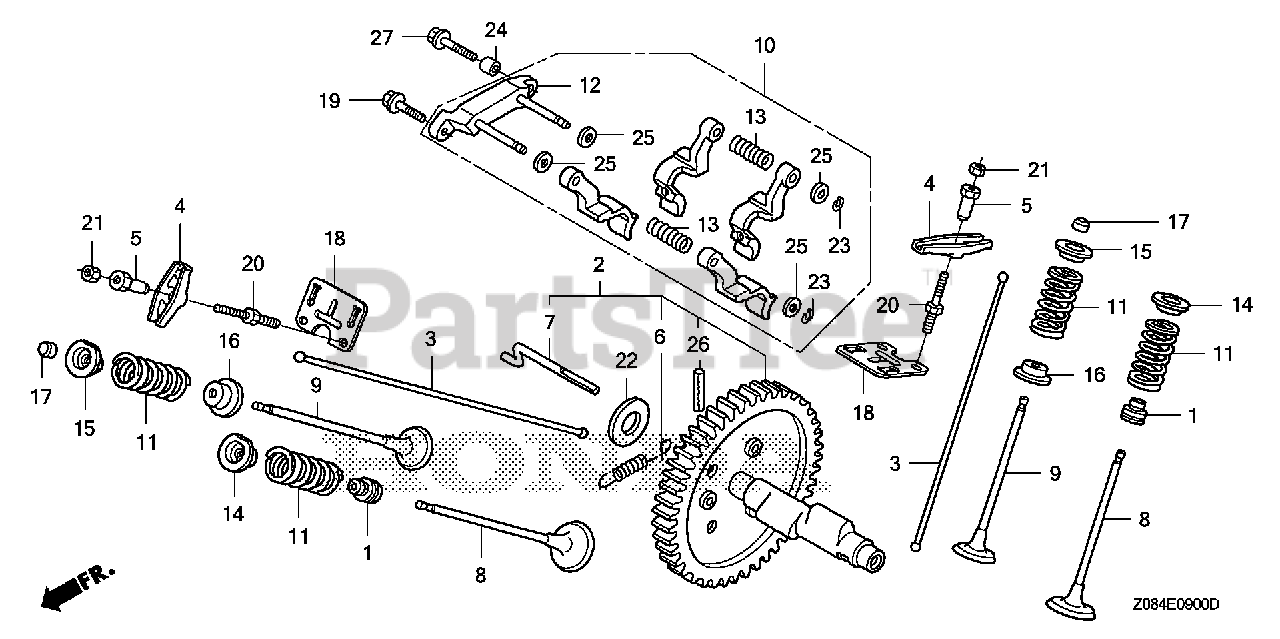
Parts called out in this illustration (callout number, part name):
1	SEAL, VALVE STEM
2	CAMSHAFT ASSY.
4	ARM, VALVE ROCKER
5	PIVOT, ROCKER ARM
6	SPRING, WEIGHT RETURN
7	PIN, DECOMPRESSION
8	VALVE, IN.
9	VALVE, EX.
10	LIFTER ASSY., VALVE
11	SPRING, VALVE
12	SHAFT, VALVE LIFTER
13	SPRING, VALVE LIFTER
14	RETAINER, IN. VALVE SPRING
15	RETAINER, EX. VALVE SPRING
16	SEAT, VALVE SPRING
17	ROTATOR, VALVE
18	GUIDE, PUSH ROD
19	BOLT, FLANGE (5X16)
20	BOLT, PIVOT (8MM)
21	NUT, PIVOT ADJUSTING
22	WASHER, THRUST (17.2MM)
23	CLIP, GOVERNOR HOLDER
24	PIN A, DOWEL (8X12)
25	WASHER, PLAIN (6MM)
26	PIN, SPRING (6X28)
27	BOLT, FLANGE (6X25)
